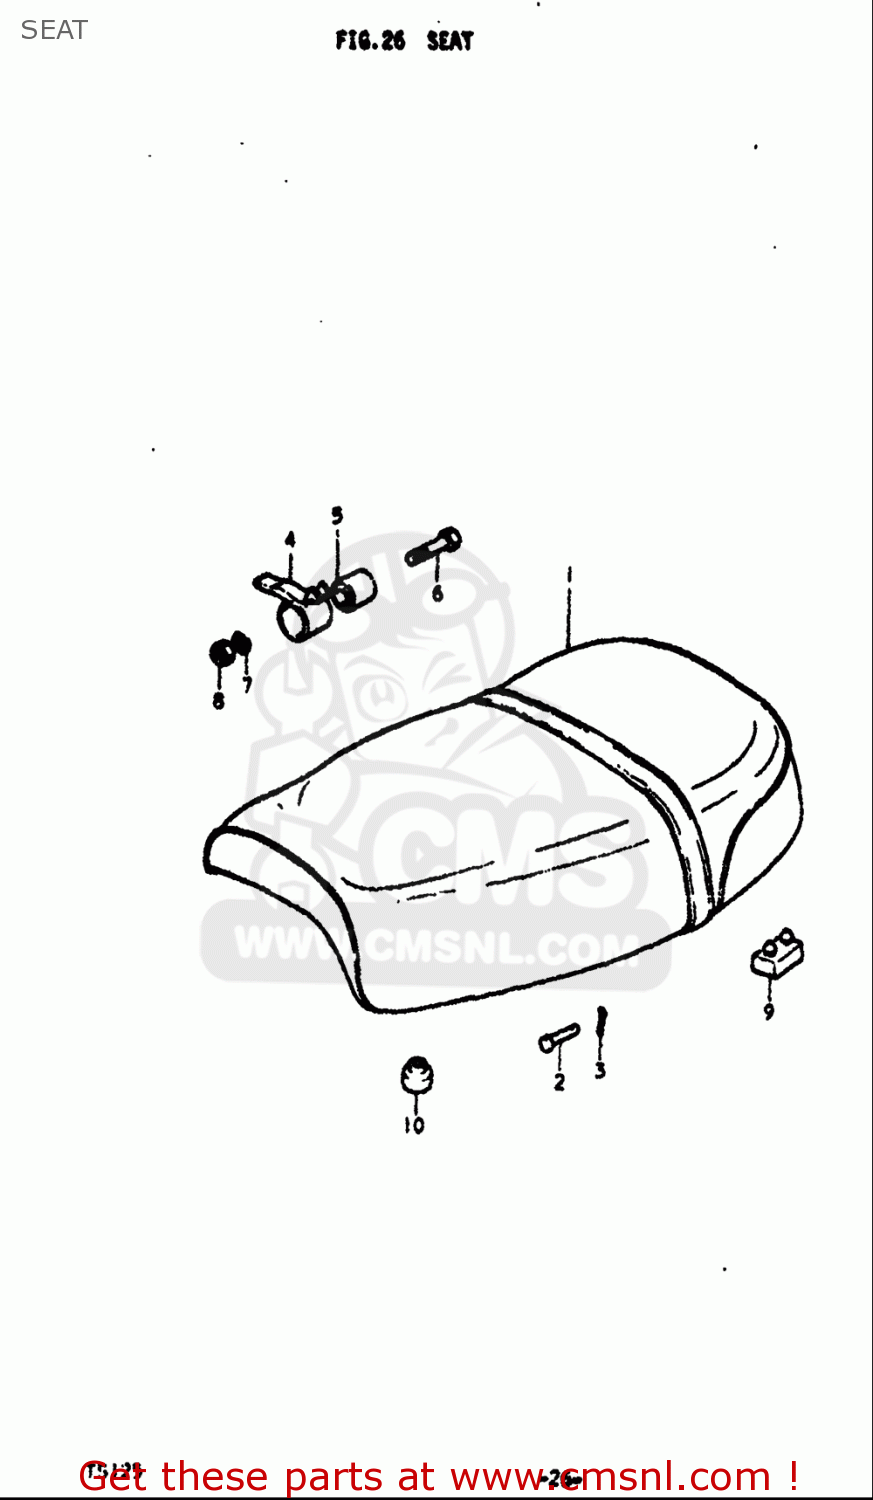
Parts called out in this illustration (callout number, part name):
2	PIN
3	PIN
5	BUSHING
6	BOLT
7	WASHER,LOCK
8	NUT
9	CUSHION
10	CUSHION(11.5X22X20)
